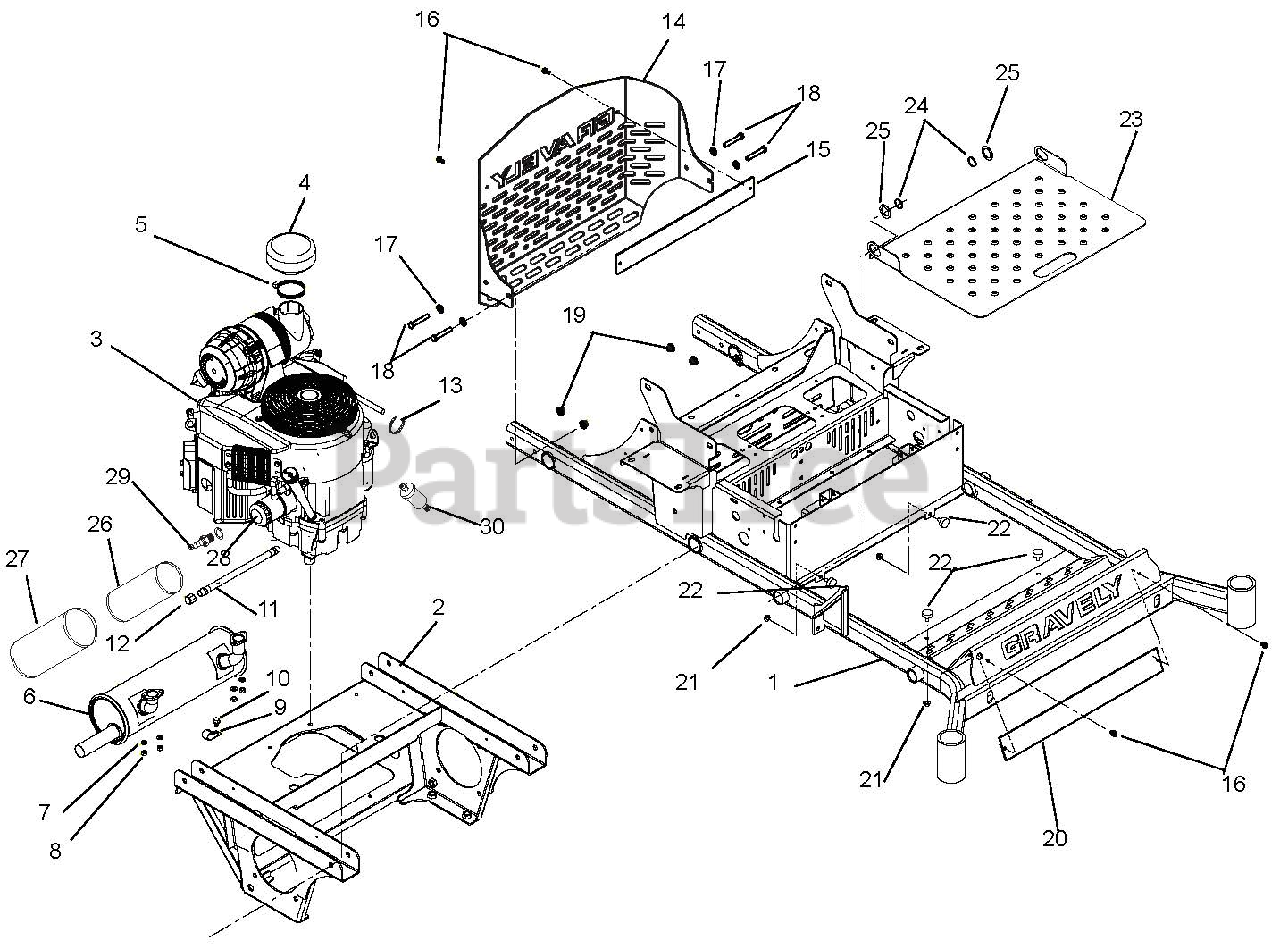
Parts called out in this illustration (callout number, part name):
1	Weldment, 52" – 66" 200PT Main Frame
2	Weldment, 200PT Axle/Engine Frame
3	Engine, Kawasaki 27HP
3	Engine, Kawasaki FX730 (26HP)
3	Engine, Kawasaki FX850 (31HP)
3	Engine, Kohler 747cc EFI
4	Rain Cap, Air Cleaner
5	Clamp, Hose 2.75 DIA Worm
6	Muffler, 27-31 Kawasaki
6	Muffler, Kawasaki Fixed 24/26HP
6	Muffler, Kohler EFI
7	Washer, Lock .31 x .078 REG YWZC
8	Nut, Locking Top M8-1.25 YWZC
10	Screw, Tap .38-16 x .50 Hex Washer Head TR YWZ
11	Hose, Hydraulic .38-11-0K M6N0-M6N0
11	Hose, Hydraulic .38-14-0K M6N0-M6N0
12	Pipe Cap 3/8 NPT Female
13	Cable Tie LG 5-1/2
14	Weldment, Bumper, Pro-Turn 200
15	Plate, Bumper, Pro-Turn 200
16	Screw, Tap .25-20 x .50 Hex Washer Head TR YWZ
17	Washer, Flat Steel .406 x .812 x .065 YWZ
18	Bolt, Hex .38-16 x 2.25 GR5 YWZC
19	Nut, Locking Nylon Flange .38-16 YWZC
20	Plate, Bumper Name Backer
21	Nut, Spin Lock Flange .312-18
22	Bumper, Rubber
23	Inspection Panel
24	Ring, Retaining, External 1.00 x .078
25	Washer, Flat Steel 1.010 x 1.505 x .062
26	Element, Inner Safety
27	Element, Outer Primary
28	Oil Filter
29	Spark Plug
30	Fuel Filter
